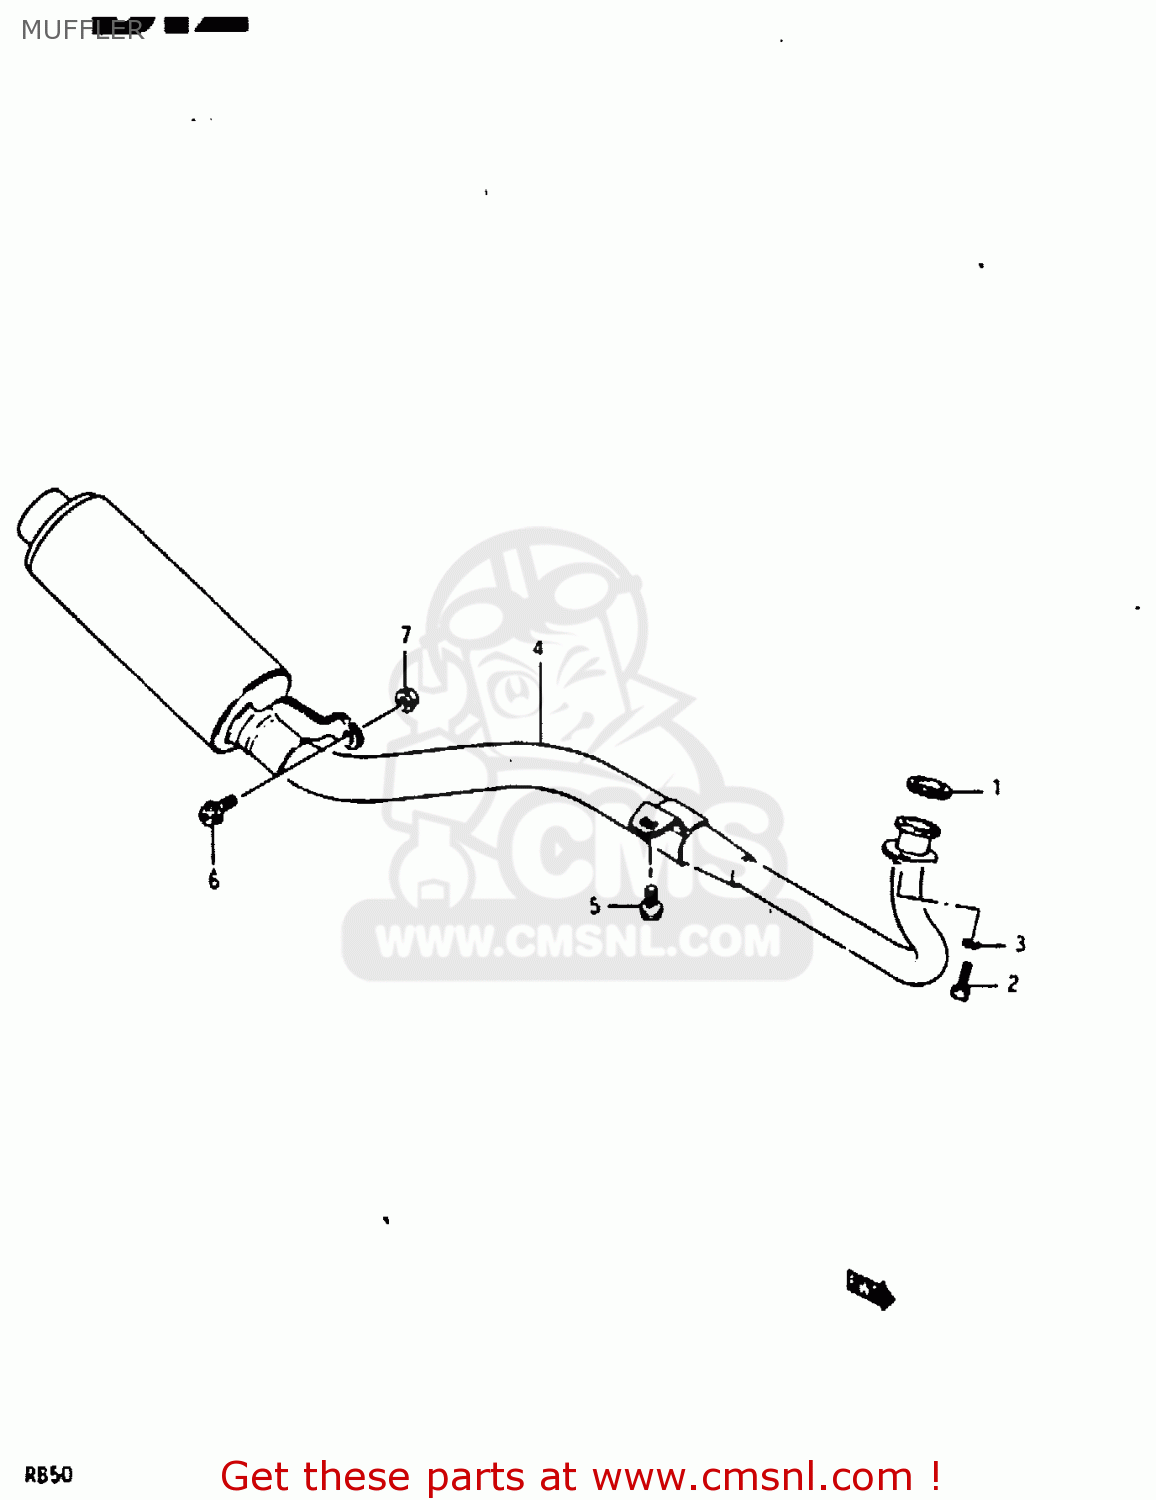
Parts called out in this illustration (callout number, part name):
1	GASKET,EXHAUST PIPE
2	BOLT
3	WASHER,LOCK
4	UITLAATSET
5	BOLT
6	BOLT
7	NUT 8MM
